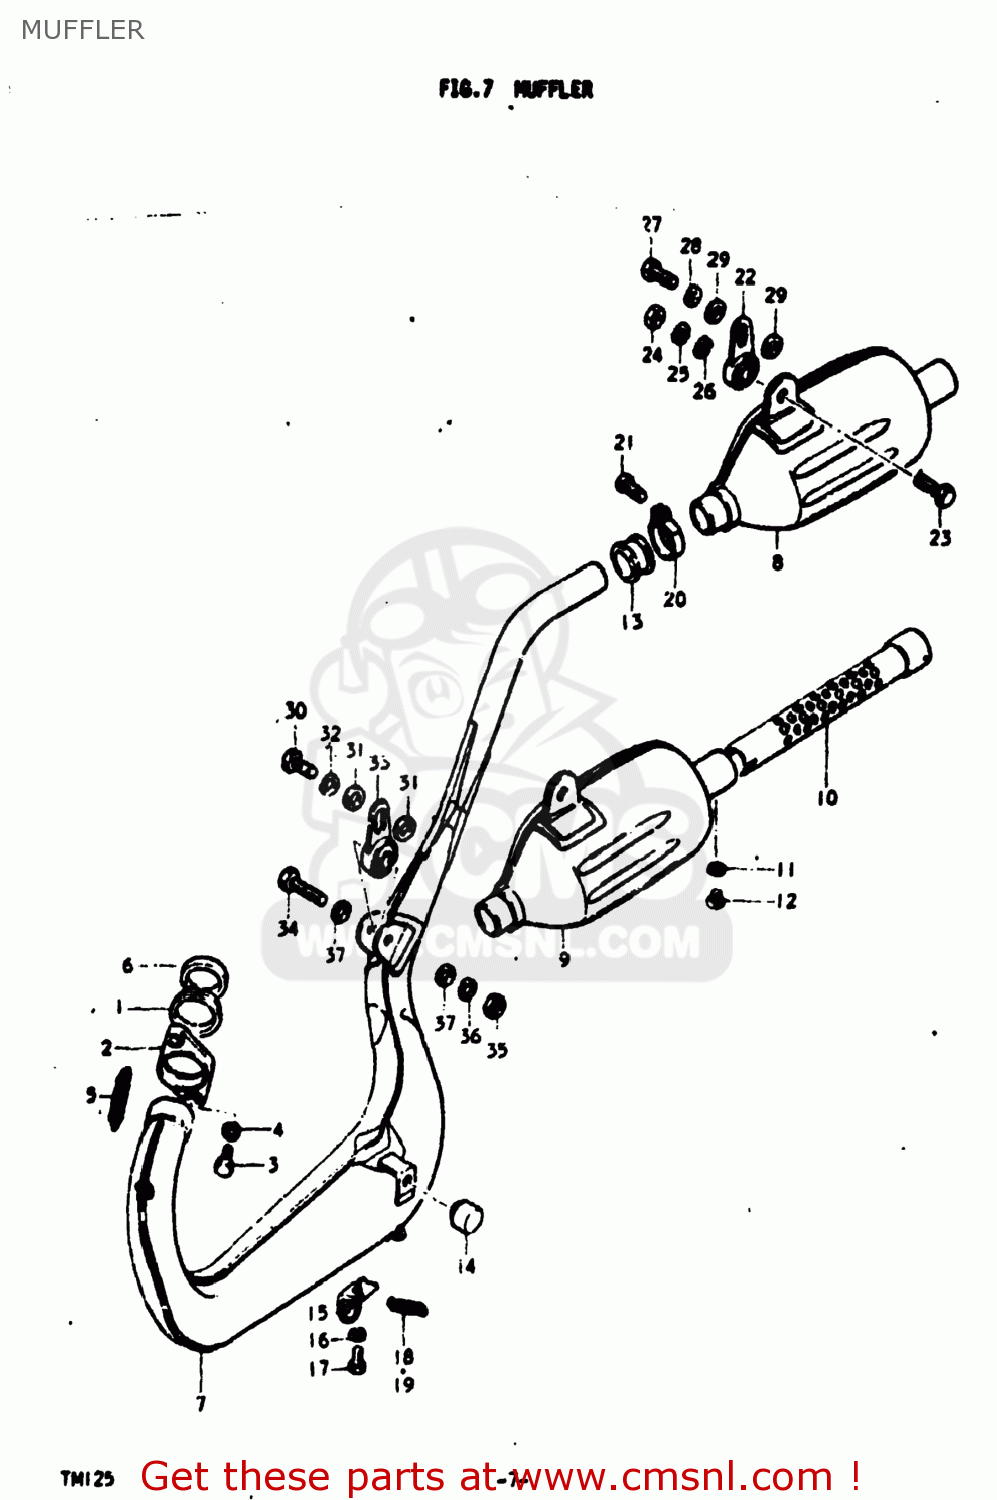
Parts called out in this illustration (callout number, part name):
1	GASKET,EXHAUST PIPE (NAS)
2	CLAMP,EXHAUST PIPE
3	BOLT
4	LOCK WASHER
5	SPRING
6	CUSHION,EXHAUST PIPE
7	BODY,MUFFLER
8	BODY,MUFFLER
9	MUFFLER ASSEMBLY
10	PIPE,MUFFLER BAFFLE
11	LOCK WASHER
12	SCREW(6X8)
13	CONNECTOR,MUFFLER
14	CUSHION(11.5X22X20)
15	BRACKET, MUFFLER STOPPER
16	LOCK WASHER
17	BOLT
18	SPRING
19	SPRING
20	CLAMP
21	SCREW
22	DAMPER,MUFFLER SUPPORT
23	BOLT
24	NUT
25	LOCK WASHER
26	WASHER
27	BOLT
28	LOCK WASHER
29	WASHER
30	BOLT
31	WASHER
32	LOCK WASHER
33	DAMPER,MUFFLER SUPPORT
34	** SUPERSEEDED
35	NUT
36	LOCK WASHER
37	WASHER
